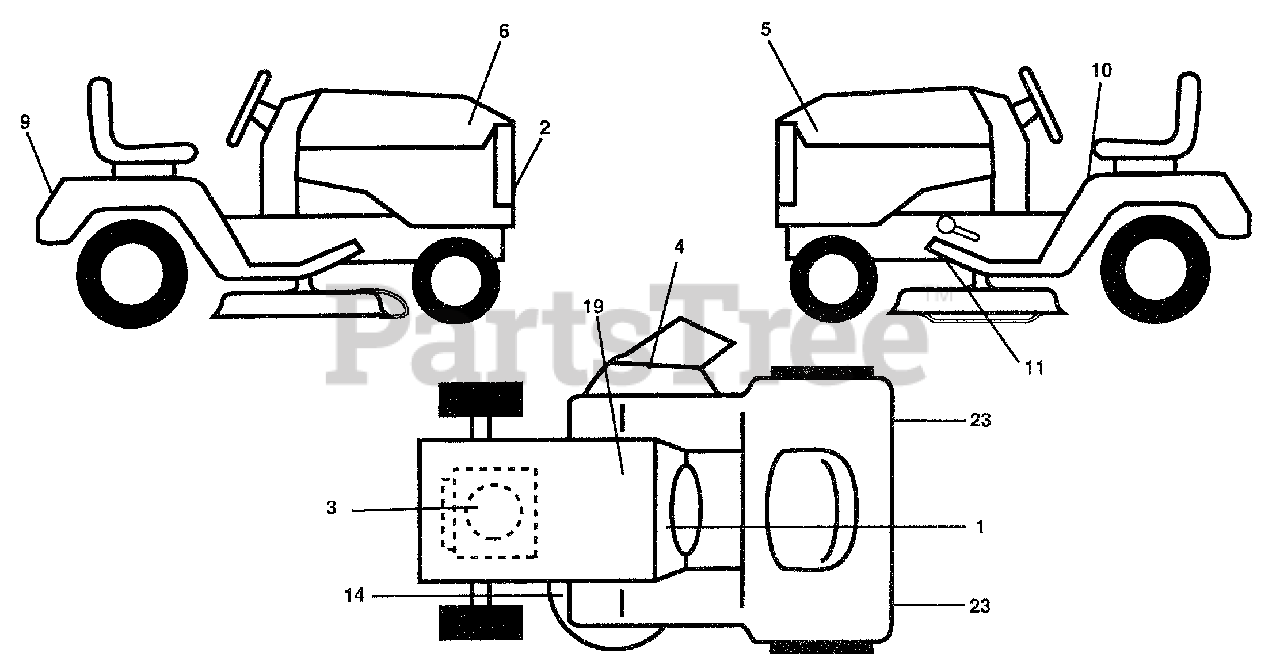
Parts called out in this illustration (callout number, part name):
1	Decal, Operating Instruction
2	Decal, Grille Husqvarna
3	Decal, Kohler 20 Hp Cmd
4	Decal, Warning Multi-Lang
5	Decal, Hood LH GT200
6	Decal, Hood RH GT200
9	Decal, Fender
10	Decal, Caution
11	Decal, Clutch/Brake
14	Decal, V-Belt Schematic
19	Decal, Battery
23	Reflector, Taillight
